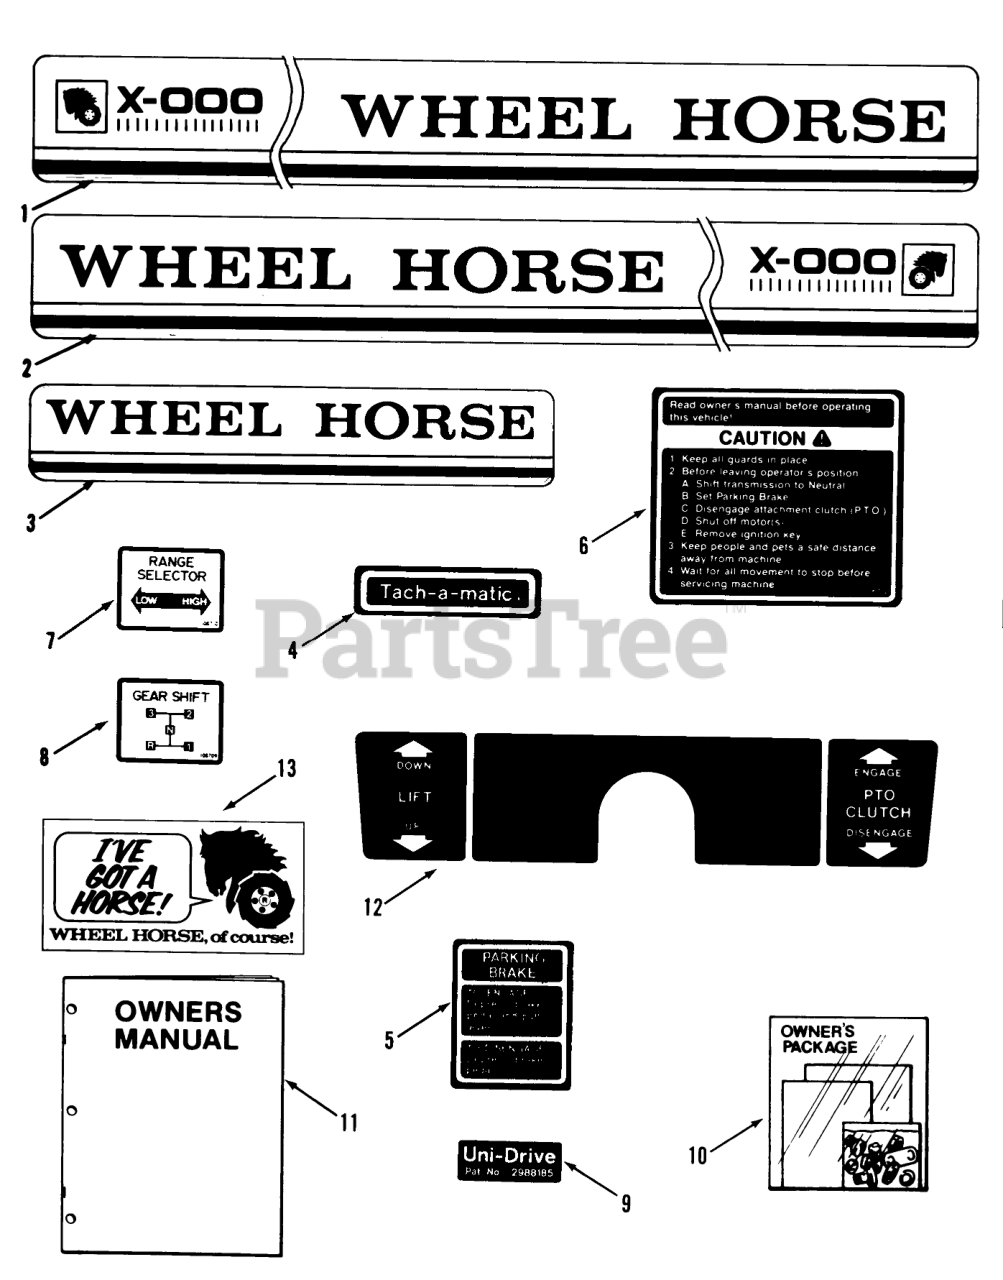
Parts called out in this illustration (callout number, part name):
1	Decal LH SB-421
1	Decal LH SK-486
2	Decal RH SB-421
2	Decal RH SK-486
3	DECAL-REAR
4	DECAL-TACHAMATIC
5	DECAL-PARKING BRAKE
6	DECAL-CAUTION
7	DECAL HI-LO
8	DECAL-SHIFT
9	Decal-Unidrive
10	Loose Parts Package SB-421
10	Loose Parts Package SK-486
11	Owner-s Manual
12	Decal-Control Housing
13	Decal-I-ve Got A Horse
